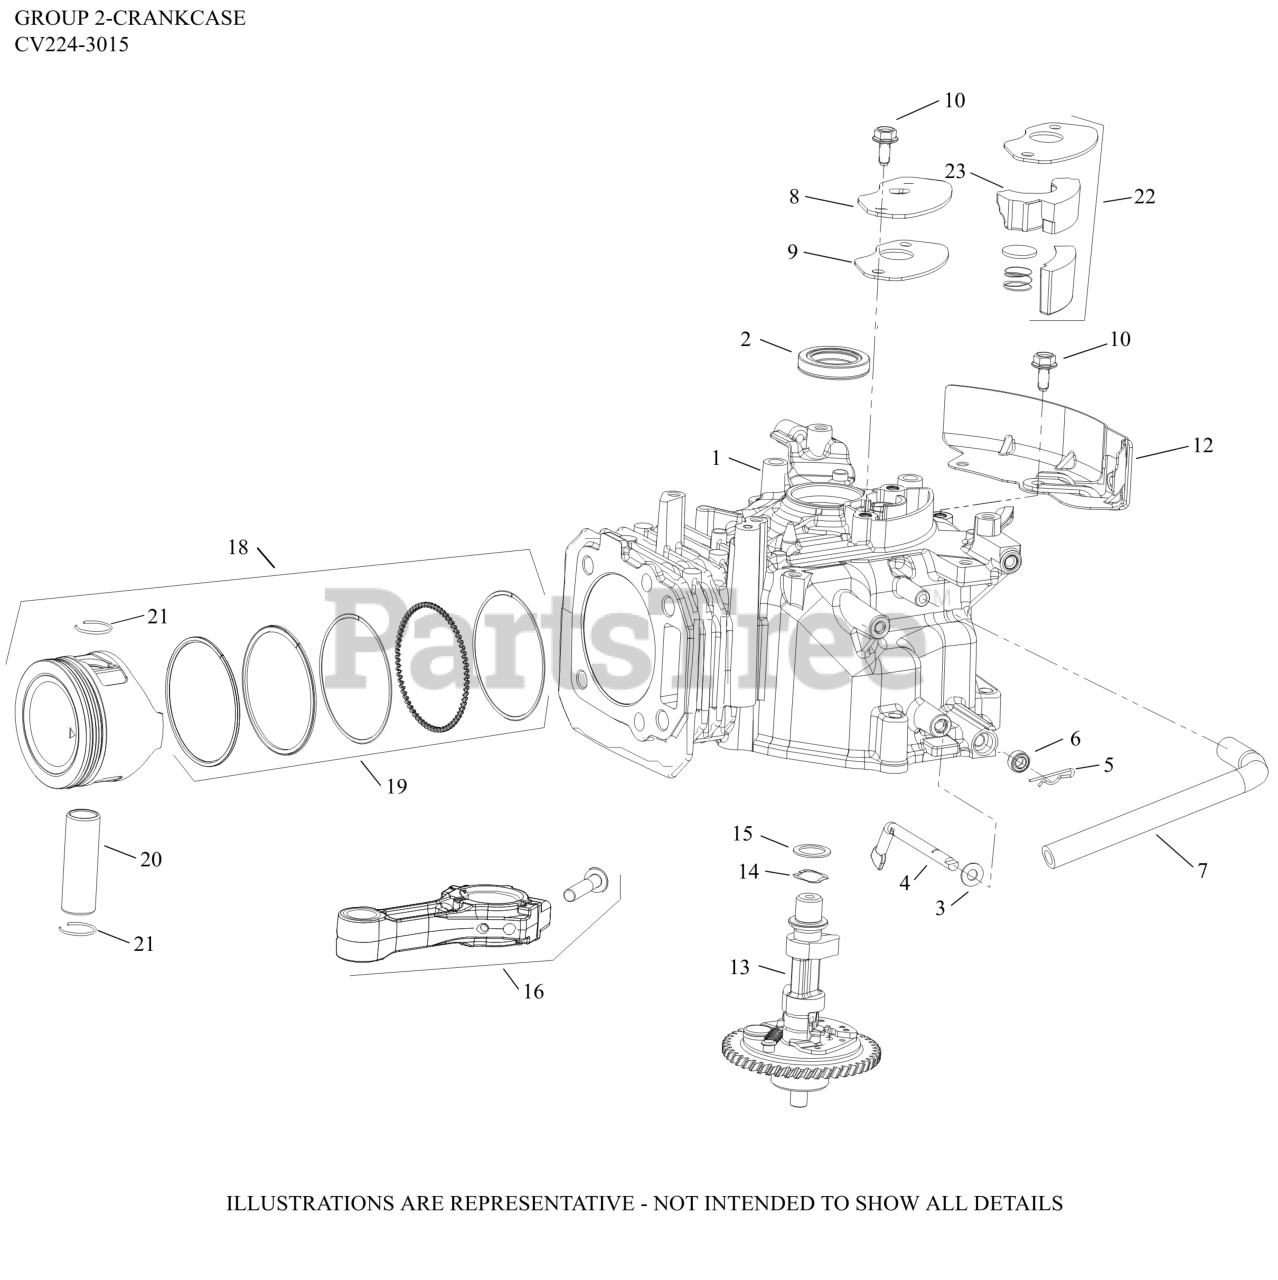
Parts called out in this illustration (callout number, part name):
1	KIT, CRANKCASE
2	SEAL, OIL
3	WASHER, FLAT (DIA 13mm O.D.)
4	SHAFT, GOVERNOR CROSS
5	CLIP, GOVERNOR SHAFT
6	SEAL, OIL
7	HOSE, BREATHER
8	COVER, BREATHER
9	GASKET, BREATHER COVER
10	SCREW, HEX FLANGE (M6)-USE 25 086 433-S
12	GUARD, REAR FINGER ASSEMBLY
13	CAMSHAFT ASSEMBLY
14	SPRING, WAVE
15	WASHER, CAMSHAFT
16	ROD, CONNECTING ASSEMBLY
18	KIT, PISTON
20	PIN, PISTON
21	RETAINER, PISTON PIN
22	KIT, BREATHER FILTER
23	FILTER, BREATHER MEDIA-USE 14 050 31-S
